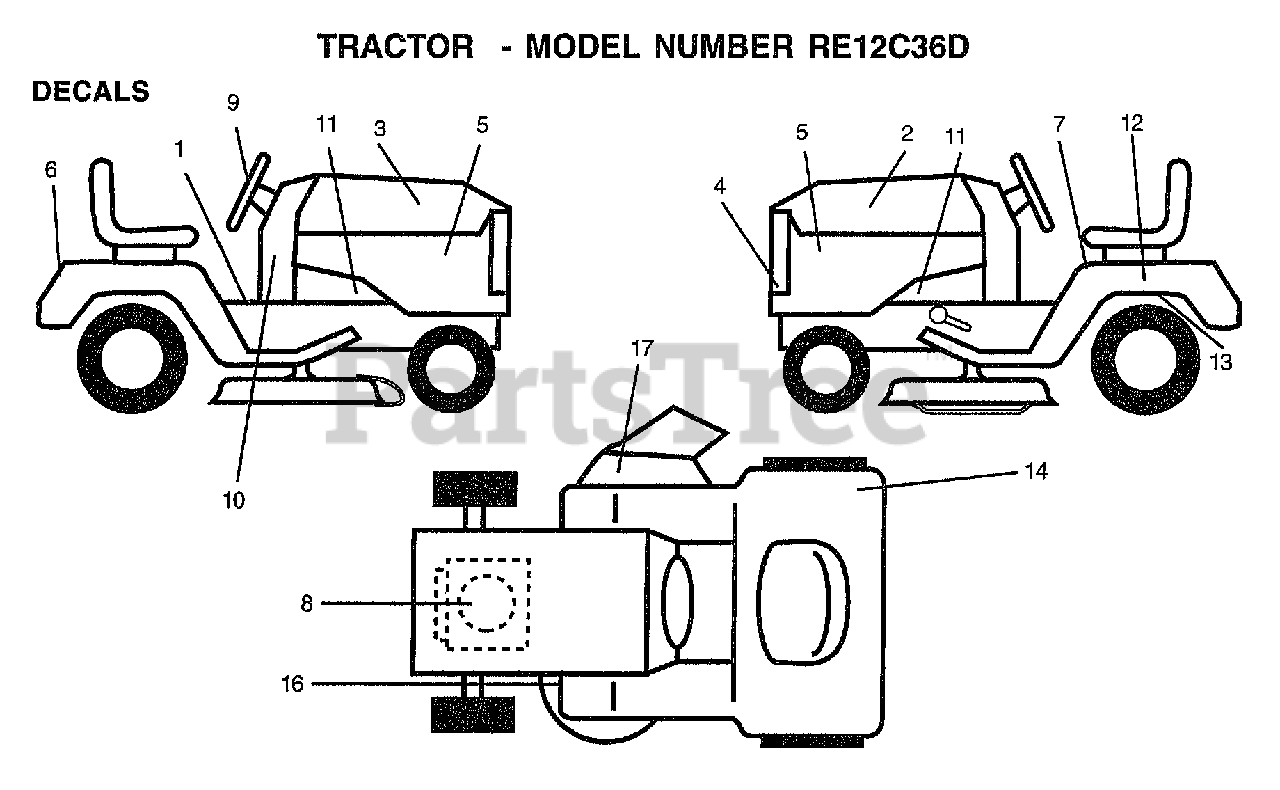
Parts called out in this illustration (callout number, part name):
1	DECAL CLUTCH/BRAK
2	DECAL HD RLY LH
3	DECAL HD RLY RH
4	GRILL DECAL
5	DECAL.INSERT.HOOD
6	FENDER DECAL
7	DECAL.READ.O.MANU
8	DECAL, ENGINE
9	"DECAL,STR WHL"
10	DECAL.EURO.ST.CE.
11	"DECAL CHASSIS,HOT"
12	DECAL.BATRY.3-3908
13	DECAL.DRAWBAR.LDL
16	DECAL.DANGER.CUTF
17	DECAL.V.BELT
